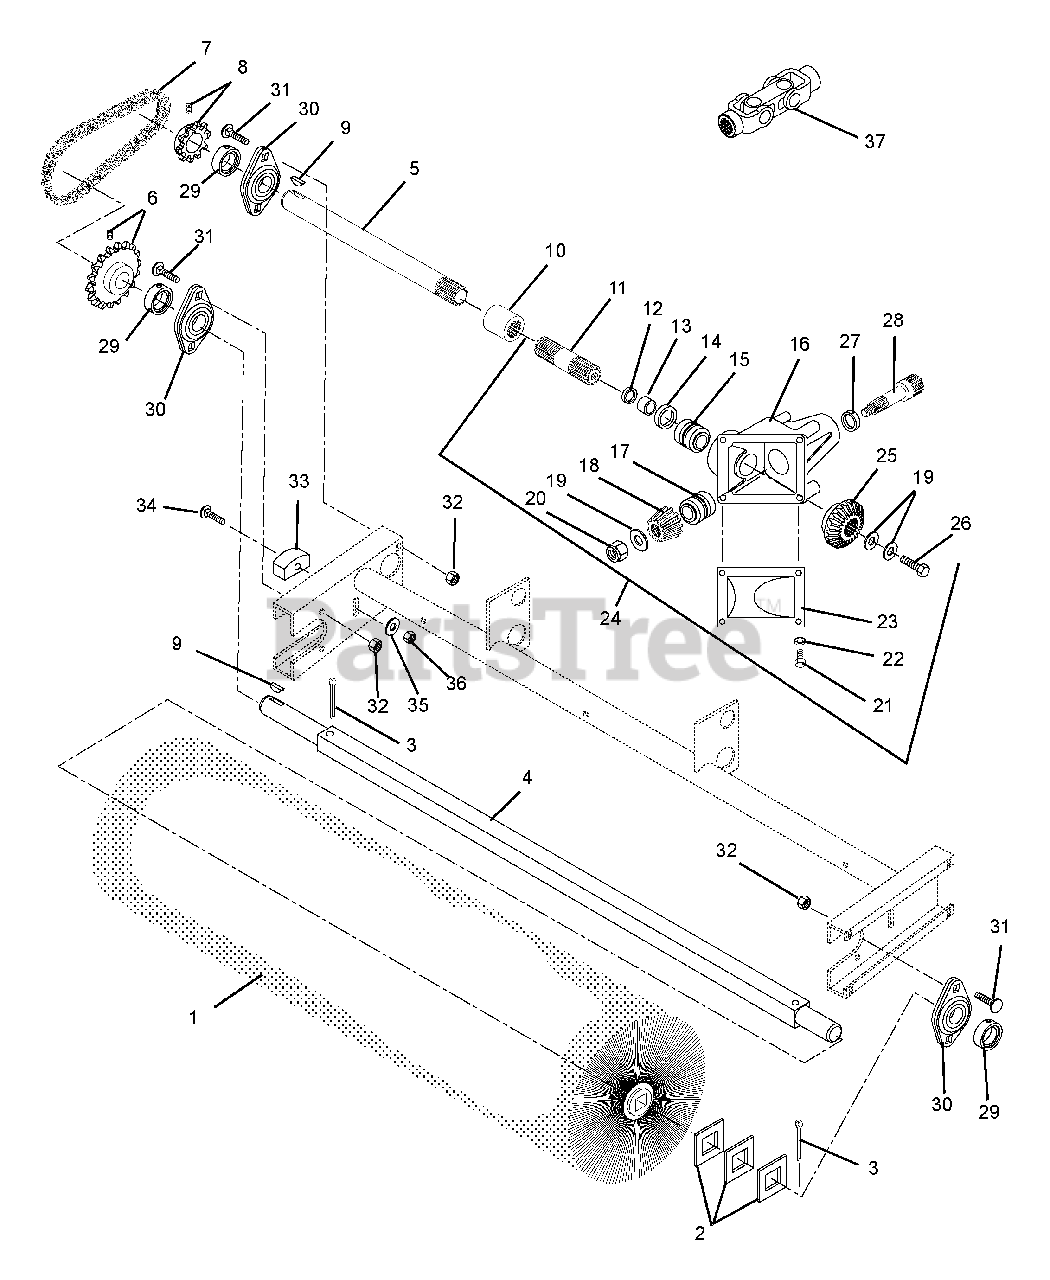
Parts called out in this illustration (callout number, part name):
1	Brush-44"
2	Spacer-Square 1.010 x 2.000 x .125
3	Pin-Cotter .25 x 2.00
4	Shaft-Power Brush
5	Shaft
6	Sprocket
7	Chain-Roller
8	Sprocket
9	Key-Woodruff .25 x .750 x .313 SAE 91
10	Coupling 1.6 x 1.37
11	Shaft-Drive
12	Ring-Retaining-External 1.106 x .95
13	Bushing, Flange 1.00 x 1.25 x 1.25
14	Seal 1.250 x 1.983 x .250
15	Bearing Assembly 1.000 x 1.980 x 1.243
16	Casting-Gear Box
17	Bearing Assembly .75 x 1.781 x 1.499
18	Gear-Bevel
19	Washer-Flat-Steel .531 x 1.06 x .095
20	Nut-Lock .50-20 UNF
21	Bolt-Hex .25-20 x .50 Grade 5
22	Washer-Lock .25 x .062
23	Cover-Gear Housing
24	Assembly-Gear Box
25	Gear-Belevel
26	Bolt-Hex .50-13 x 1.25 Grade 5
27	Seal-Oil 1.000 x 1.690 x .250
28	Shaft
29	Bearing w/ Collar 1.00 x 2.047 x .844
30	Flange-Mounting 2-Hole 52mm x 3.75
31	Bolt-Round Head Square Neck .31-18 x .75 Grade 5
32	Nut, Locking, Nylon .312-18
33	Block, Tension
34	Bolt-Round Head Square Neck .25-20 x 2.00
35	Washer-Flat-Steel .281 x .62 x .065
36	Nut-Locking-Center .25-20
37	Assembly, Double Universal Joint
